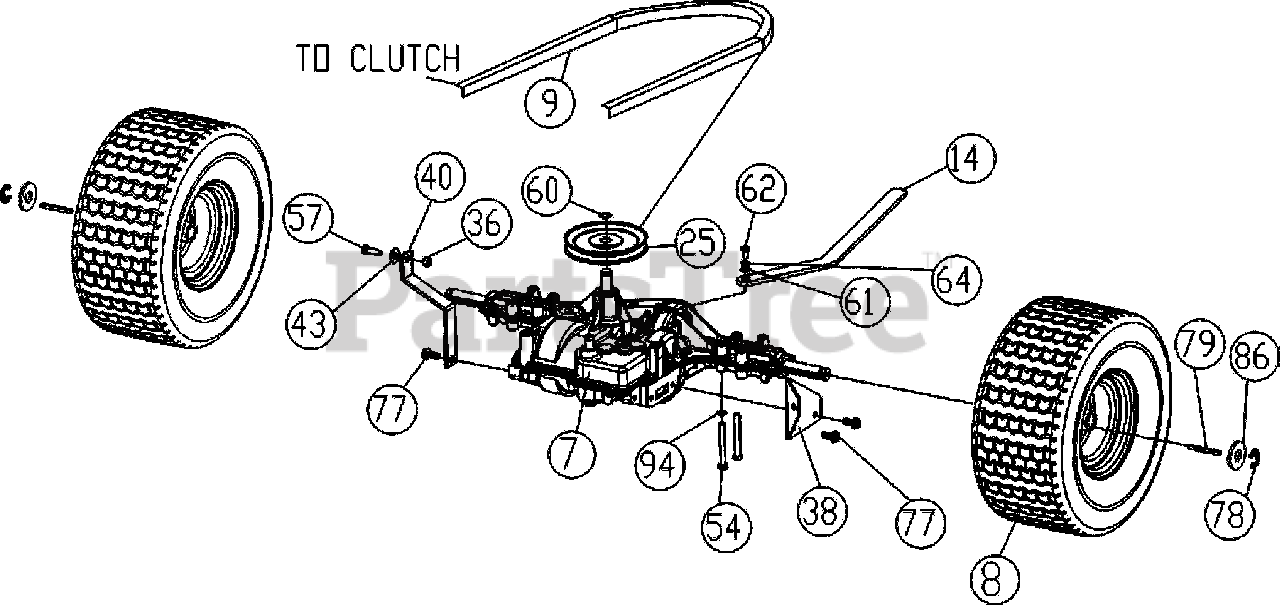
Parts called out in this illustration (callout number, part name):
7	Transaxle HP
8	Wheel 13" x 6.50 Pneu. SP
9	Belt 4L x 33
14	Bar Shift HP
25	Pulley 5" x 5/8 ID
38	Bracket Mount Clutch Cable
40	Bar Brace Transmission
43	Washer 5/16 Flat ZP
54	Screwcap 5/16"-18 x 2 3/4" HCS ZP
57	Washer Lock 3/8" S/T Med
60	Snap Ring 5/8"
61	Washer 1/4" SAE
62	Screwcap 1/4"-28 x 1/2" HCS Gr. 5 ZP
64	Washer Lock 1/4" External Tooth
77	Screw self tap 5/16" x 3/4" HEX
78	Ring Snap 0.750
79	Key 3/16" sq x 2 1/8"
86	Washer .765" ID x 1.25 OD x .06"
94	Washer Lock 5/16" S/T Med
